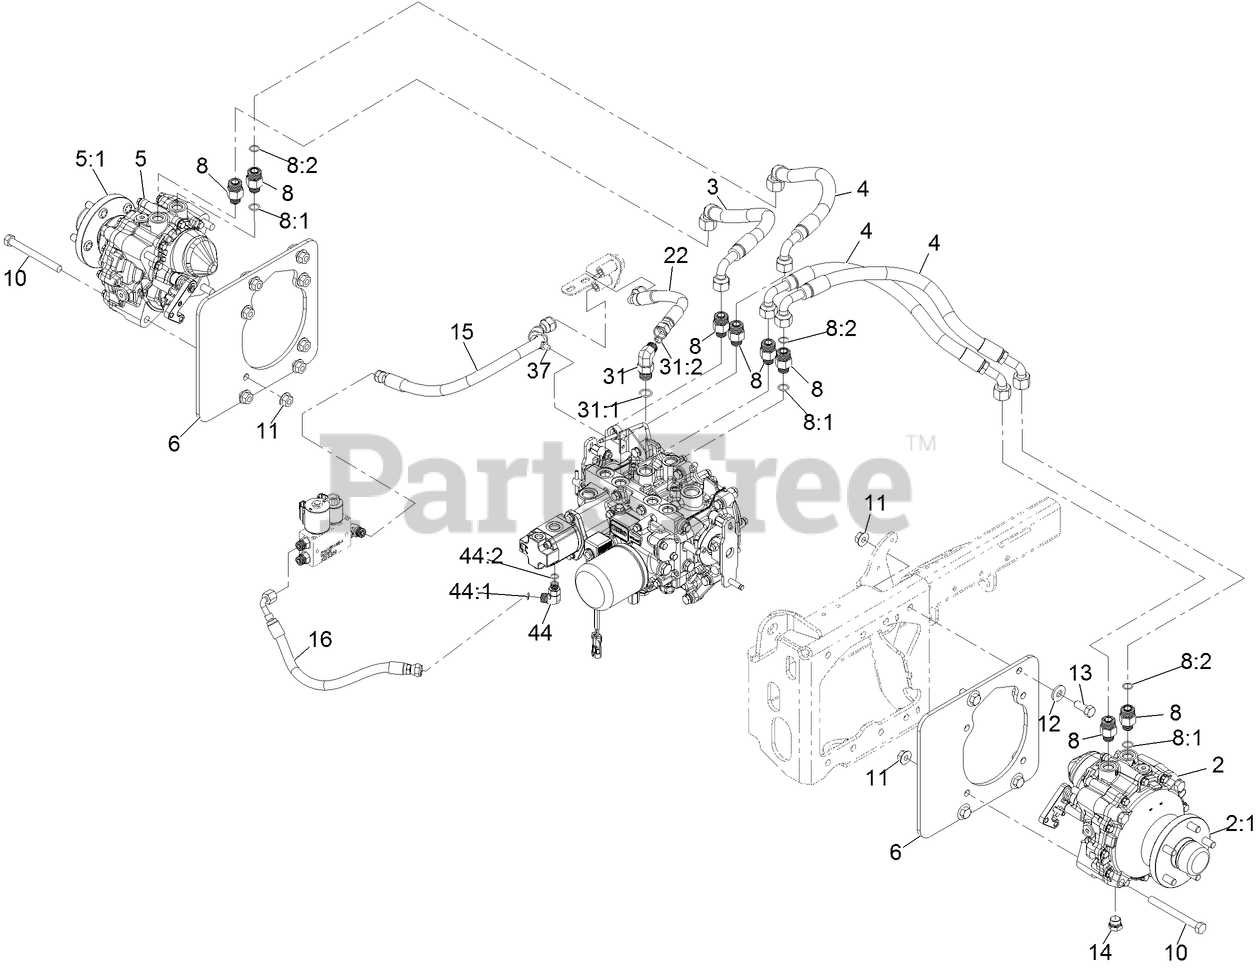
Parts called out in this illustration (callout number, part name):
2	MOTOR-HYD, LH
2:1	5 STUD WHEEL HUB KIT
3	HOSE ASM
4	HOSE ASM
5	MOTOR-HYD, RH
5:1	5 STUD WHEEL HUB KIT
6	PLATE-MOTOR
8	FITTING-STRAIGHT
8:1	O-RING
8:2	O-RING
10	SCREW-HH
11	NUT-HHF
12	WASHER-SPRING
13	SCREW-HH
14	PLUG-MAGNETIC
15	HOSE ASM
16	HOSE ASM
22	HOSE ASM
31	FITTING-ELBOW, 90 DEG
31:1	O-RING
31:2	O-RING
37	CLIP-TIE
44	FITTING-ELBOW, 90 DEG
44:1	O-RING
44:2	O-RING
